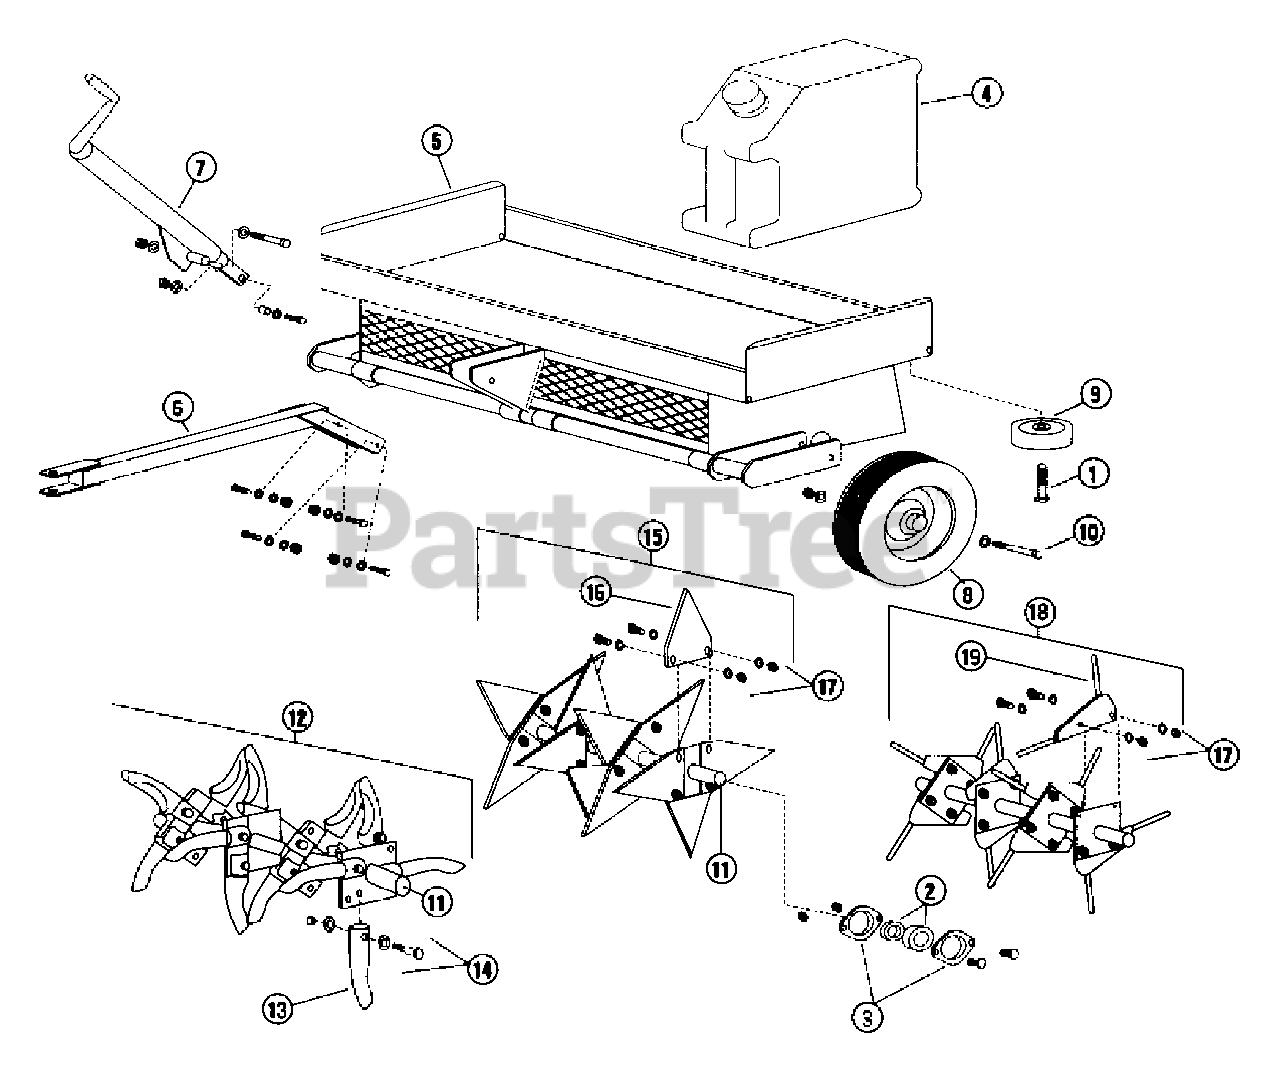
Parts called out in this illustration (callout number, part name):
1	Bolt
2	Bearing, 1" with lock collar
3	Stamping kit w/fasteners
4	Weight container, set of six
5	Chassis weldment
6	Tow bar with bolt kit
7	Jack towable aerator with bolt kit
8	Wheel, 12" X 3" semi pneumatic
8	Bearing, roller 3/4"
9	Wheel, 1 1/4" X 5"
10	Bolt kit
11	Rotor, TripleAire
12	Rotor assembly, coring tine complete with bearings
12	Rotor assembly, coring tine complete without bearings
13	Tine set, towable aerator 16 each, per rotor
13	Tine, 1/2" closed spoon, each
14	Fastener kit, coring tine set, per rotor
15	Rotor assembly, slice blade complete with bearings
15	Rotor assembly, slice blade complete without bearings
16	Slice blade set, 16 each, per rotor
16	Slice blade, each
17	Fastener kit, spike or slice blade, per rotor
18	Rotor assembly, spike complete with bearings
18	Rotor assembly, spike complete without bearings
19	Spike plate set, 8 each, per rotor
19	Spike plate, each
